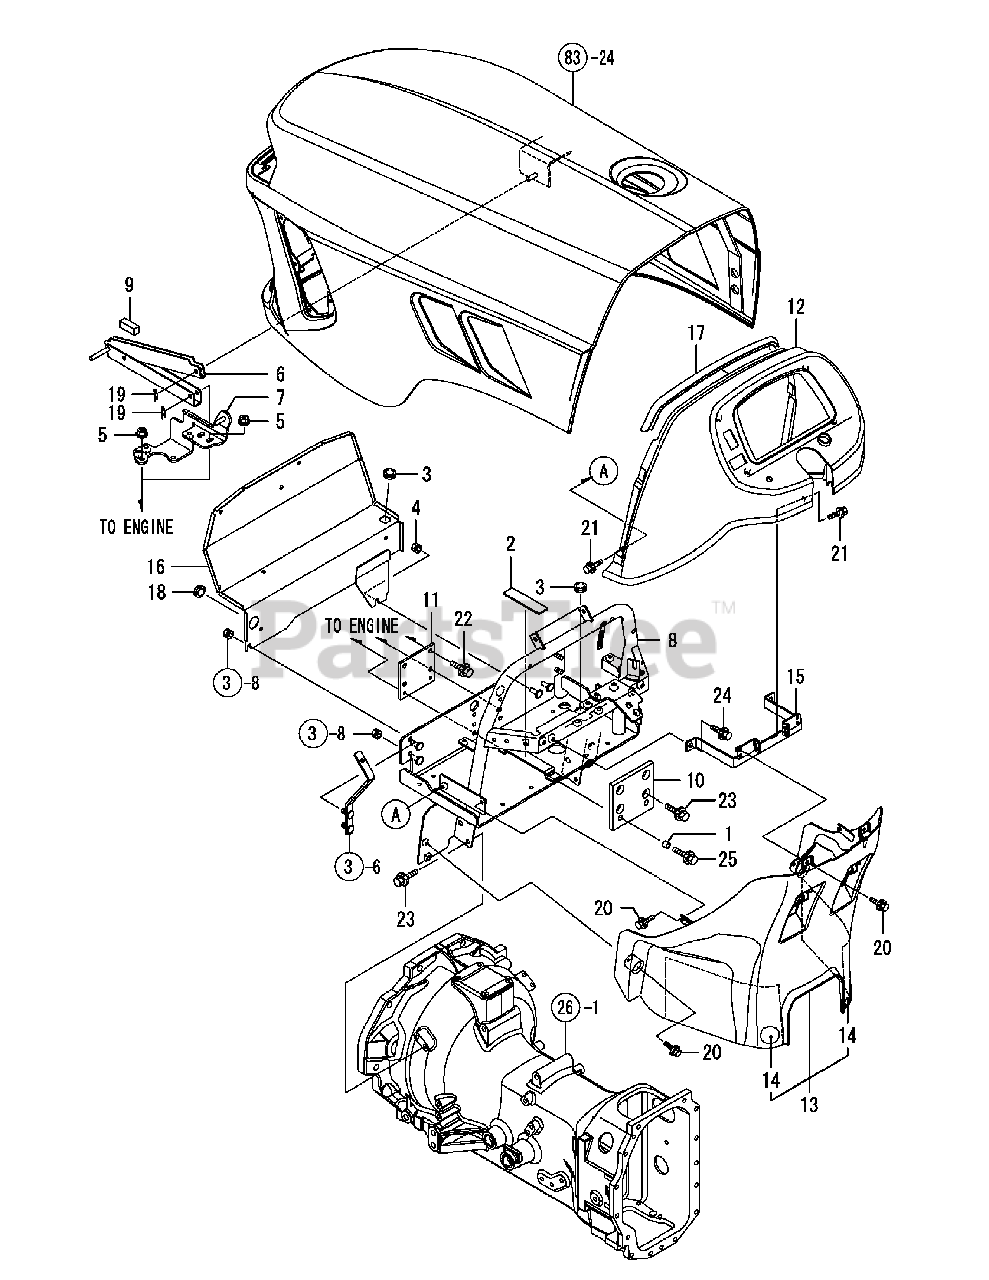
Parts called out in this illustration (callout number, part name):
1	Spacer 8X10X10
2	Rubber, 100X25X3
3	Rubber, Grommet
4	Nut W/Washer 8
5	Nut W/Washer 8
6	Bonnet Stand Assy
8	Stay Assy, Dashboard
9	Stopper, Stand
12	Dashboard, Upper
13	Dashboard Assy, Lower
15	Stay, Db Lower
16	Plate Cmp, Air Cut
17	Seal, Dashboard
18	Grommet 30 W/Film
19	Snap Pin (Jaso 8)
